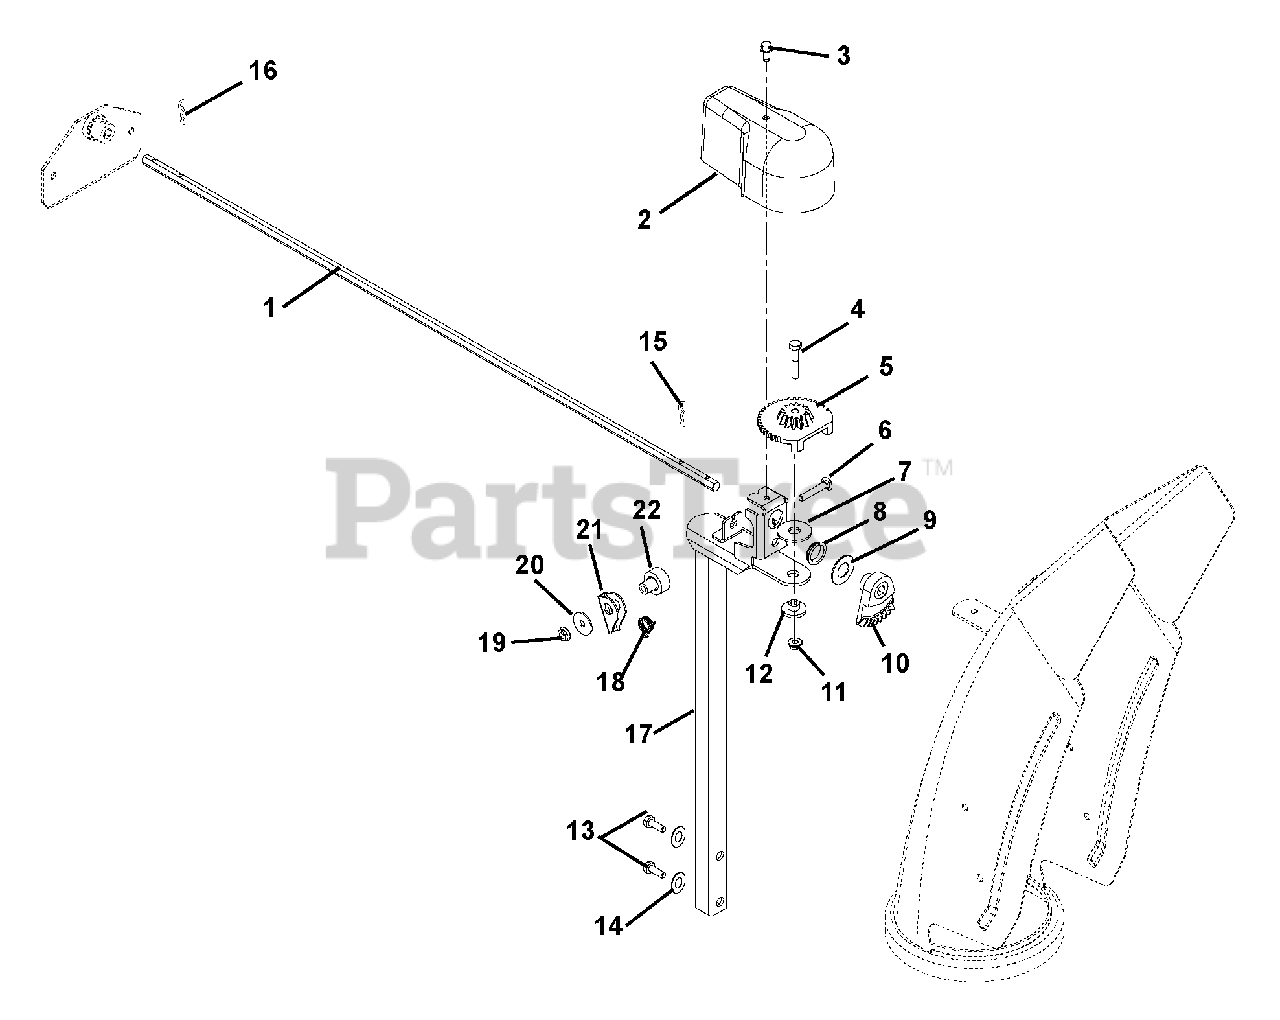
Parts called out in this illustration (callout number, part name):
1	ROD, CHUTE ROTATION-HEX
2	COVER, CHUTE GEAR
3	@SCR-TAP .25-20X.50 HWH TR YWZ
4	@BLT-HEX .25-20X1.50 GR5 YWZC
5	GEAR, CHUTE
6	@BLT-RDHDSQNK .25-20X1.50 G5YZ
7	WSHR-FL-NYL .47X1.38X.09
8	BUSHING, POLYLINER-.75 SNAPIN
9	WSHR-FL-STL.754X1.125X.062YWZC
10	GEAR, CHUTE-ACTUATION
11	@NUT-LK-TOP-FLG .25-20 YWZC
12	BSHG-FLG .265X.448X.375X1.00
13	@BLT-HEX .38-16X1.75 GR5 YWZC
14	@WSHR-LK .38X.094 REG YWZC
15	CLIP, SPRING
16	HAIRPIN, #7 CLIP .094X2.31 YWZ
17	PEDESTAL, CHUTE SUPPORT
18	SG-TORS
19	@NUT-LK-TOP-FLG .25-20 YWZC
20	WSHR-FL-STL .281X1.000X.063
21	ARM, LOCKING
22	BUSHING, LOCK ARM
